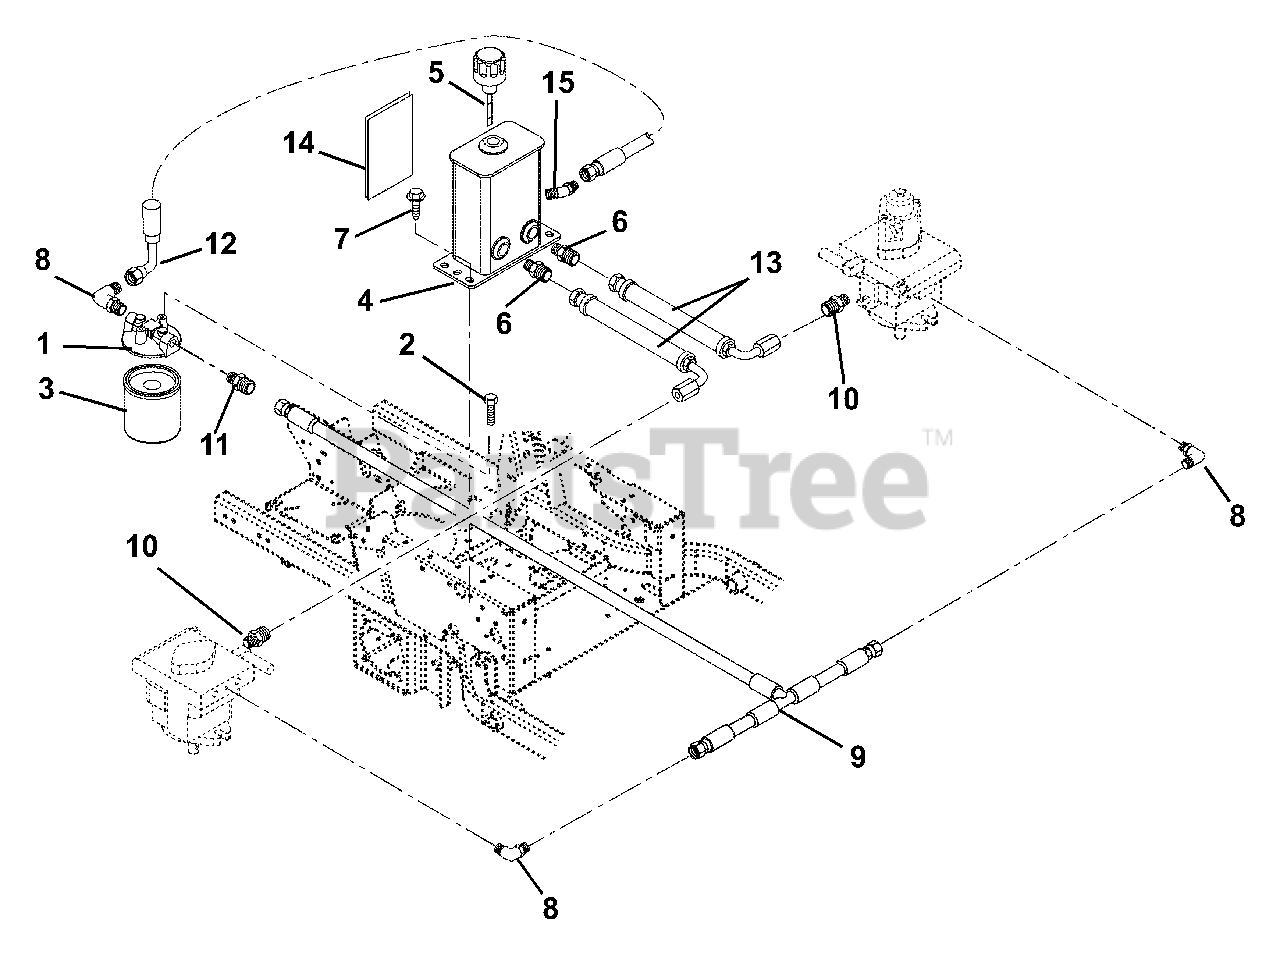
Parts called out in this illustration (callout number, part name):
1	HEAD, FILTER
2	@BLT-HEX .25-20X.50 GR5 YWZC
3	ELEMENT, FILTER BE-40-0
4	WMT, HYDRAULIC TANK
5	BREATHER, DIPSTICK
6	FTG, HYD STR M8O-M4F
7	@SCR-TAP .38-16X.75 HWH TR YWZ
8	FITTING, HYD (6 C5OLO)
9	HOSE, TEE ASSM .38
10	FITTING, HYD (4-6 F5OLO)
11	FITTING, HYD (6 F5OLO)
12	HOSE, HYD .38-9-0K F6F0-F6F9
13	HOSE, HYD .25-3-0K F4F0-F4F9
14	SHEILD, HEAT 5.50X4.50
15	FTG, HYD 45DEG M6F-M8O
